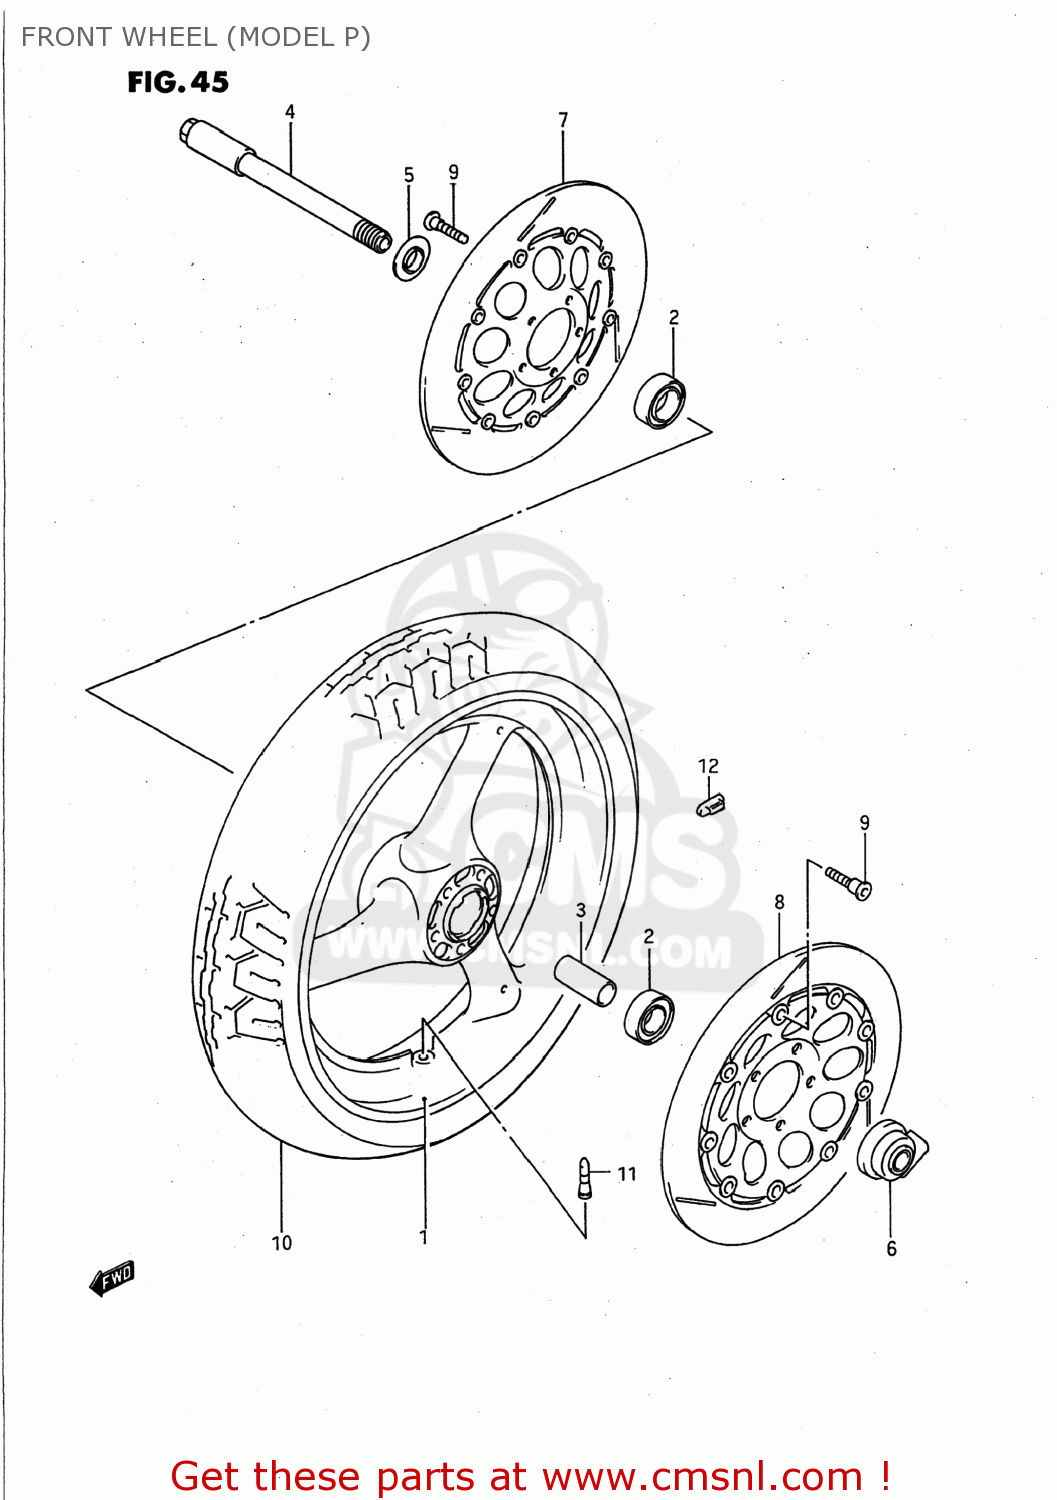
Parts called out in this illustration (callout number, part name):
1	WHEEL,FRONT (17XMT3.50)
2	BEARING
3	SPACER(20.8X27.2X74)
4	AXLE,FR
5	SPACER,FR HUB BEARING,R
6	BOX ASSY,SPEEDOMETER GEAR
7	DISC,BRAKE
8	DISC,BRAKE
9	BOLT 8X33
10	TIRE,FRONT
11	VALVE ASSY,WHEEL RIM(TR412)
12	BALANCER,WHEEL
